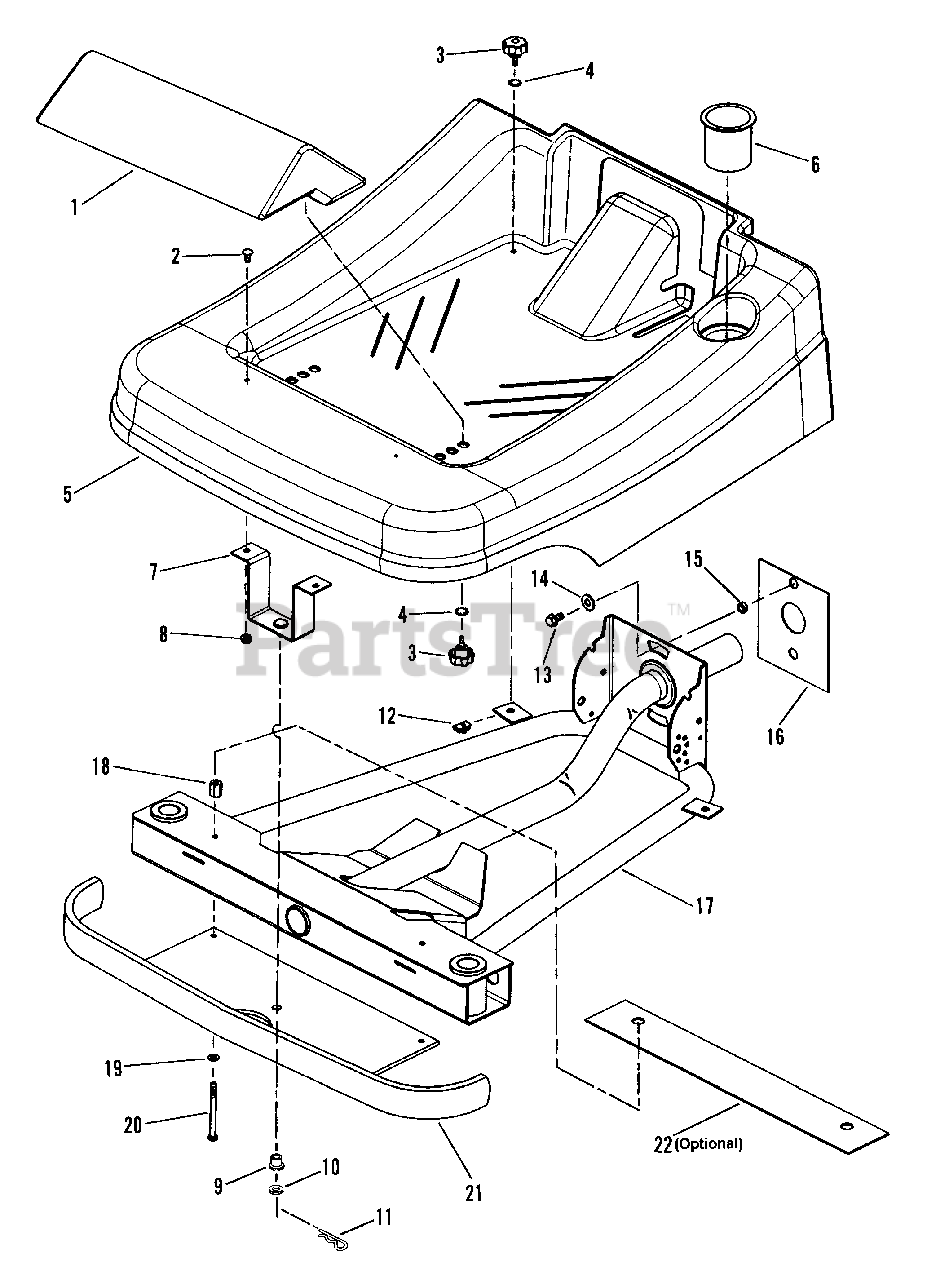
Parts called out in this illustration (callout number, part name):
1	FOOT REST
2	BOLT, 5/16-1 8 x 5/8" Carriage, Grade 5
4	WASHER, 1/4" Internal/External Lock
5	COVER, Front Frame
7	BRACKET, Front Cover
8	NUT, 5/16-18 Flange Center Lock
9	BUSHING
10	WASHER, 3/8" Flat
11	HAIRPIN, 3/32 x 1-1/2"
12	FASTENER, "U" Type
13	SCREW, 3/8-16 x 1" Hex Washer Face, Self-Tapping
14	WASHER, 3/8" Flat
15	SPACER, Front Frame Pivot
16	PLATE, Front Frame Pivot
17	FRAME, Front
18	STAND-OFF, 5/16-18 x 5/8" Hex
19	WASHER, 5/16" Split Lock
20	BOLT, 5/16-18 x 3-3/4"
21	BUMPER, Front
22	PLATE, Front Frame Ballast
